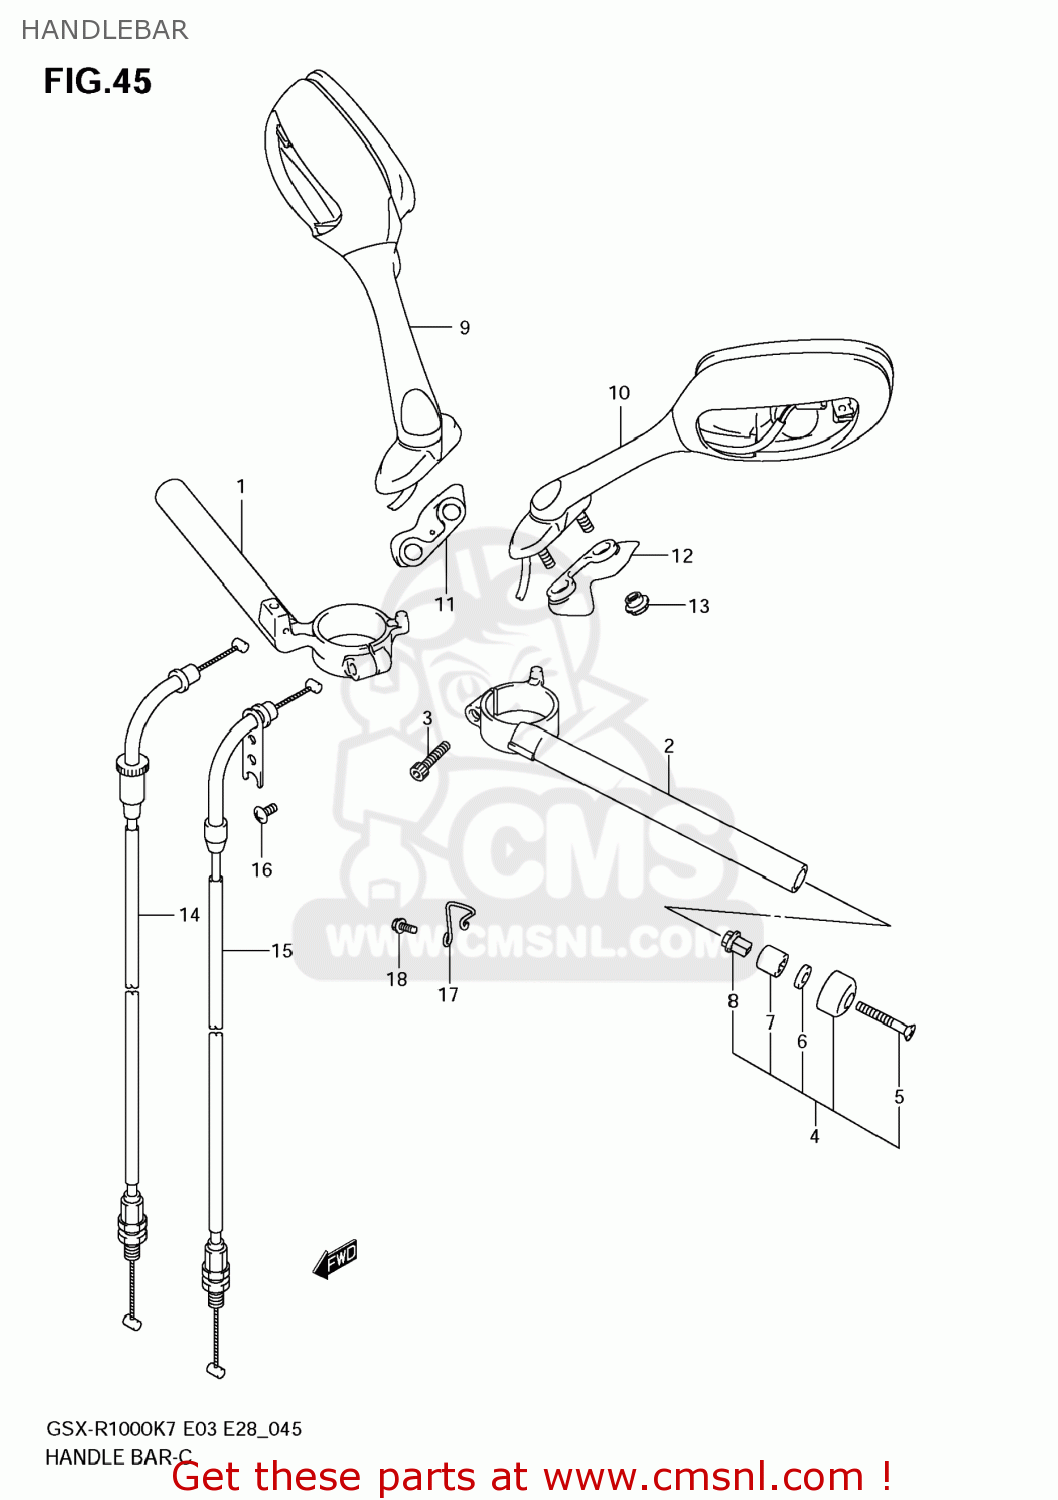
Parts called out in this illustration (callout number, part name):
1	HANDLEBAR,R
2	HANDLEBAR,L
3	BOLT(8X32)
4	BALANCERSET
5	SCREW
6	WASHER(6.5X16X4)
7	EXPANDER,HANDLE BALANCER
8	NUT,HANDLE BALANCER
9	MIRROR ASSY,RE
10	MIRROR ASSY,RE
11	CUSHION,RR VIEW MIRRROR,R
12	CUSHION,RR VIEW MIRRROR,L
13	NUT,RR VIEW MIRROR
14	CABLE ASSY,THROTTLE NO.1
15	CABLE ASSY,THROTTLE NO.2
16	SCREW
17	GUIDE,THROTTLE CABLE
18	BOLT
